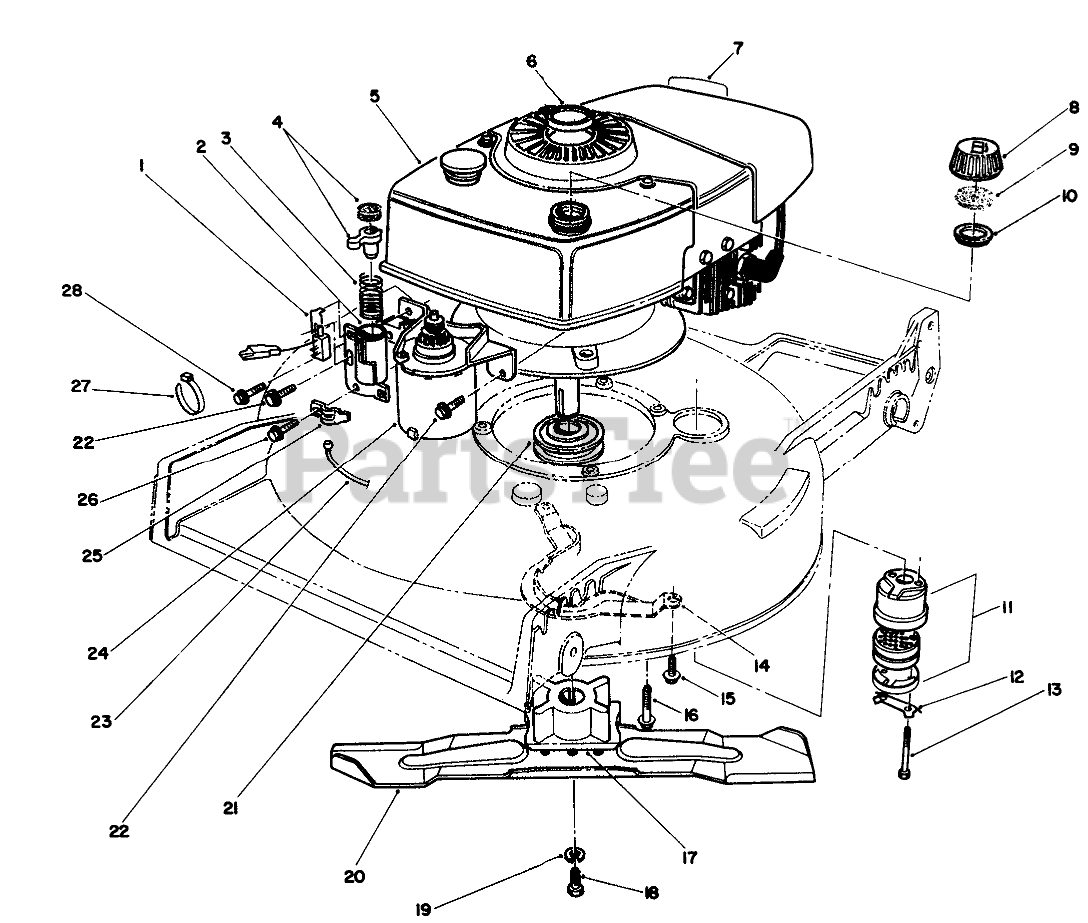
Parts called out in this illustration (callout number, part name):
1	PUSH BUTTON SWITCH
2	TUBE W A
3	COMPRESSION SPRING
4	BRAKE PAD/PLUNGER ASM
6	PLUG BUTTON
7	Decal-Maintenan
8	Gas Cap (Incl. Ref. #9 & 10)
9	GASKET
10	GAS CAP BAFFLE
11	Muffler Assembly (Incl. Ref. #12 & 13)
12	CLIP - LOCKING
13	SCREW-HH
14	BELT GUIDE
15	SCREW-HWHTF
16	3/8-16 X 2 CAPSCREW
17	BLADE RETAINER
18	SCREW-BLADE
19	WASHER-LOCK
20	BLADE-21in
21	PULLEY-DRIVE, ZONE START
22	SCREW
23	BRAKE CABLE
24	STARTER MOTOR ASM
25	CABLE CLAMP
26	SCREW
27	TIE-CABLE
28	Screw
